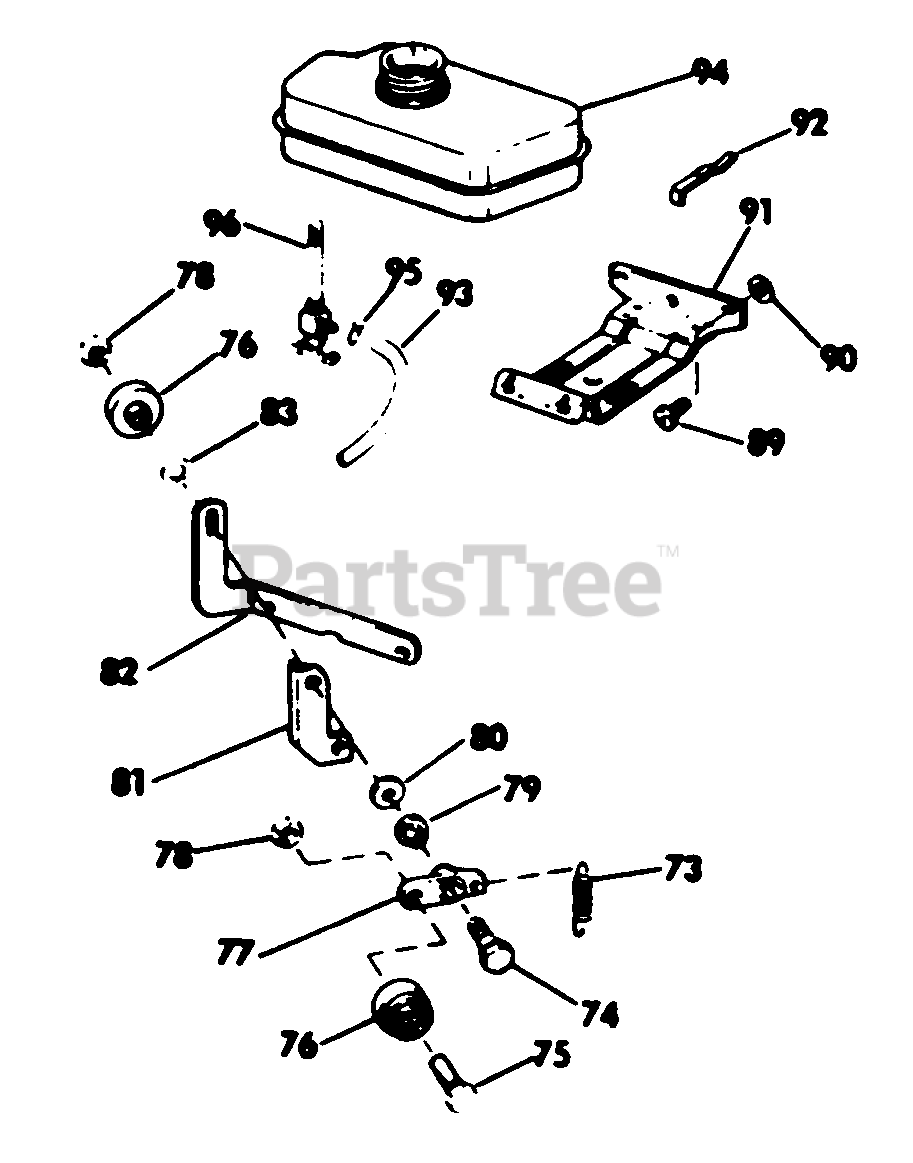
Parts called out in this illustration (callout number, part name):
74	SHOULDER BOLT
76	PULLEY & BEARING ASSY.
79	GROMMET
81	BRACKET
82	BRACKET
83	LOCK WASHER
90	WASHER
91	FUEL TANK BRACKET
93	FUEL LINE
94	FUEL TANK
95	HOSE CLAMP
96	SHUT-OFF VALVE
